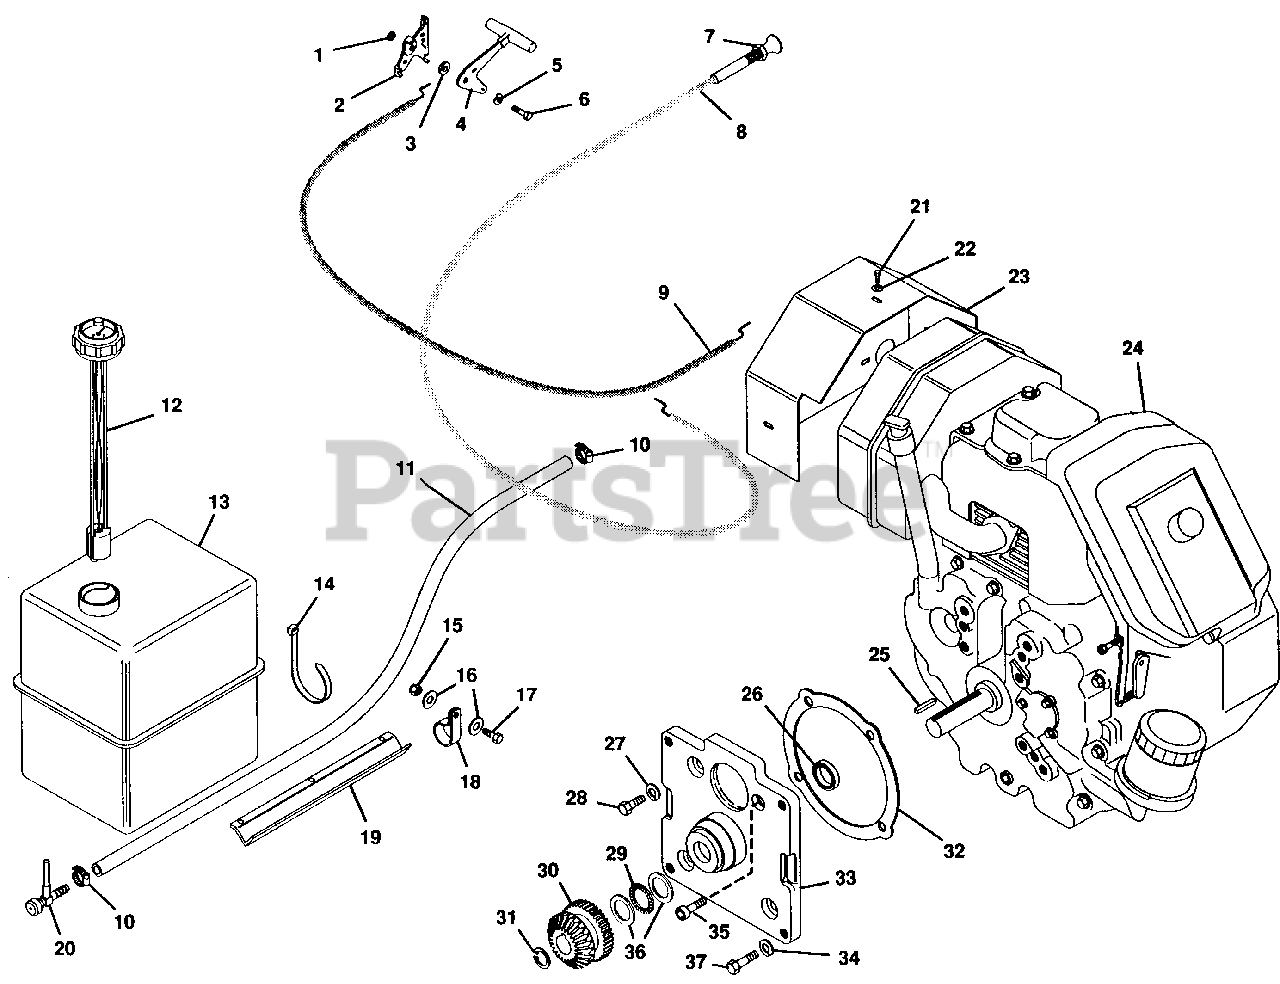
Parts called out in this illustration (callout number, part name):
1	NUT, LOCK 1/4-28
2	BRACKET, MOUNTING
3	WASHER, FRICTION
4	ASSEMBLY, KNOB AND LEVER
5	WASHER, SPRING
6	BOLT, HEX 1/4-28X.75
7	NUT, JAM 3/8-24
8	CONTROL, CHOKE
9	ASSEMBLY, CHOKE CONDUIT
10	CLAMP, HOSE
11	LINE, FUEL
12	GAUGE, GAS
13	TANK, FUEL
14	TIE, CABLE
15	NUT, LOCK 5/16-18
16	WASHER, FLAT .344X.688X.065
17	BOLT, HEX 5/16-18X1.00
18	CLAMP, NYLON
19	SHIELD, HEAT
20	VALVE, FUEL 90 DEG. REVERSE FLOW
21	SCREW, 8-18X.50
22	WASHER, FLAT #10 .219X.5X.049
23	SHIELD, HEAT 14 HP KOHLER
24	ENGINE, 14 HP KOHLER
25	KEY, SQUARE .250X1.250
26	SEAL, OIL 1.125X1.628X.250
27	WASHER, LOCK 7/16 SP HEAVY
28	BOLT, HEX 7/16-14X1.125
29	BEARING, THRUST 1.127X1.740X.078
30	GEAR, SPUR AND BEVEL, INPUT
31	RING, RETAINING 1.125 SHAFT
32	GASKET, ADAPTOR
33	ADAPTOR, ENGINE
34	WASHER, LOCK 1/2 REG.
35	SCREW, CAP 7/16-14X1.0 SHD
36	RACE, BRG 1.125X1.75X.123/.126
37	BOLT, HEX 1/2-13X1.25
NS	NUT, LOCK 10-32
NS	SCREW, MACHINE 10-32X.50 PHD
